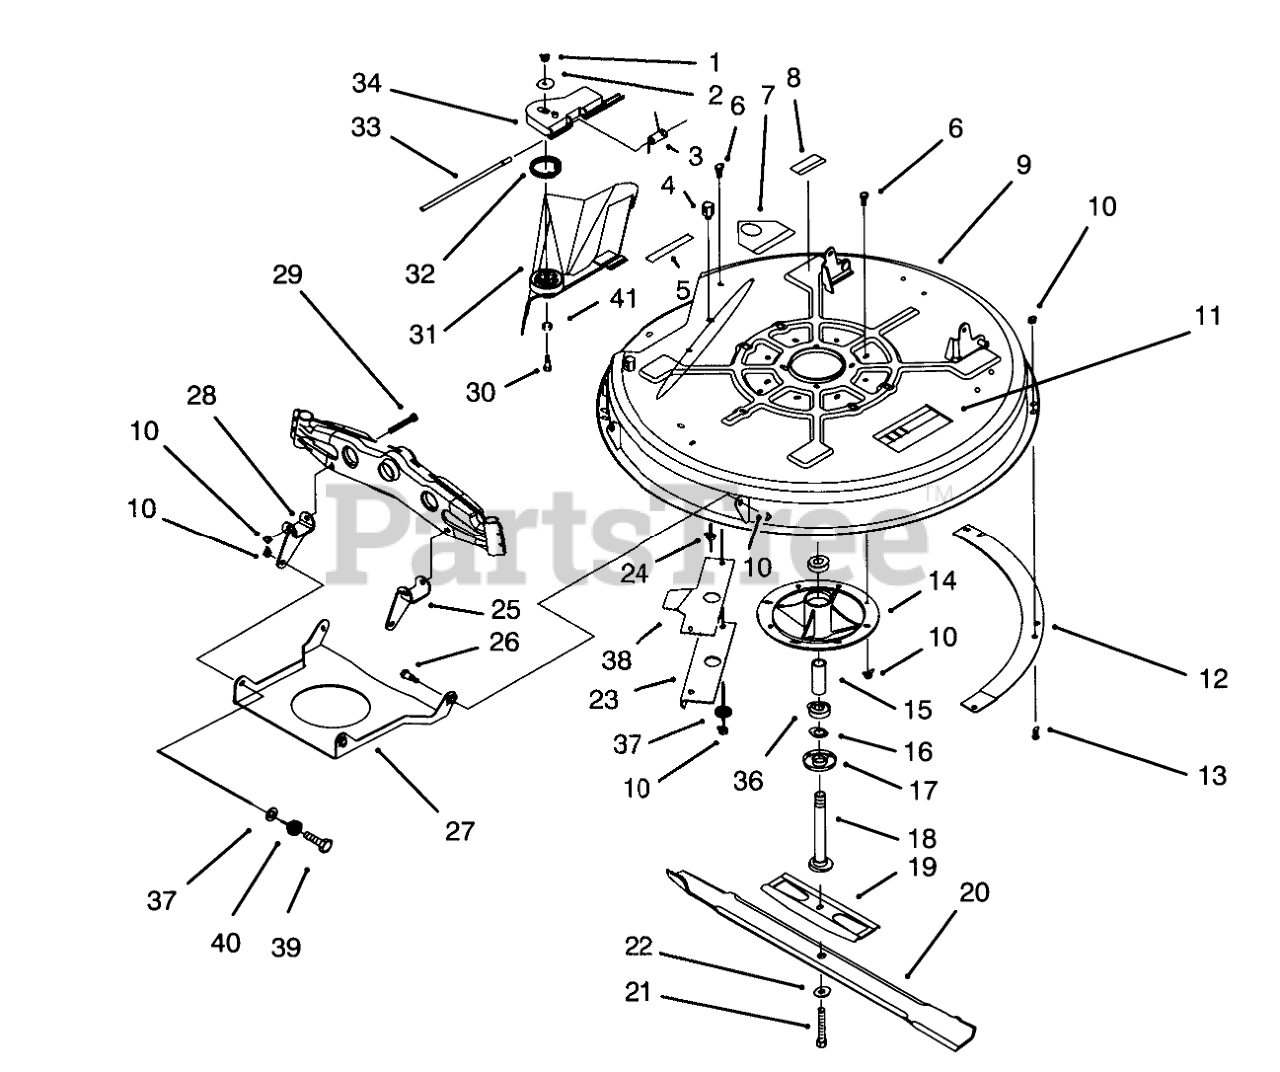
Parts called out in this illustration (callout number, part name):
1	NUT-LOCK, NI
2	WASHER-FLAT
3	SPRING-TORSION
4	POST-PIVOT
5	DECAL-DANGER, DEFLECTOR
6	SCREW-HH
7	DECAL-DANGER
8	DECAL-WARNING
9	Cutter Deck-32"
10	NUT-LOCK, NI
11	DECAL-DANGER, THROWN OBJECT
12	Ring-Deck
13	SCREW-PPH
14	SPINDLE
15	SPACER-BEARING
16	SPACER-HARDNED
17	SHIELD-BEARING
18	SHAFT-SPINDLE
19	STIFFENER
20	Blade
21	SCREW-HH
22	WASHER-BELLEVILLE
23	Baffle Deck
24	NUT-LOCK, NI
25	Bracket-L.H.
26	BOLT-SHOULDER
27	Pan-Front Deck Susp.
28	Bracket-R.H.
29	SCREW-HH
30	Bolt-Shoulder
31	Deflector-Double Pivot
32	SPRING-TORSION
33	ROD-HINGE, DEFLECTOR
34	PIVOT-HINGE, DEFLECTOR
36	BEARING-BALL
37	WASHER-PLAIN
38	Ramp-Deflector
39	SCREW-HH
41	BRONZE SPACER
